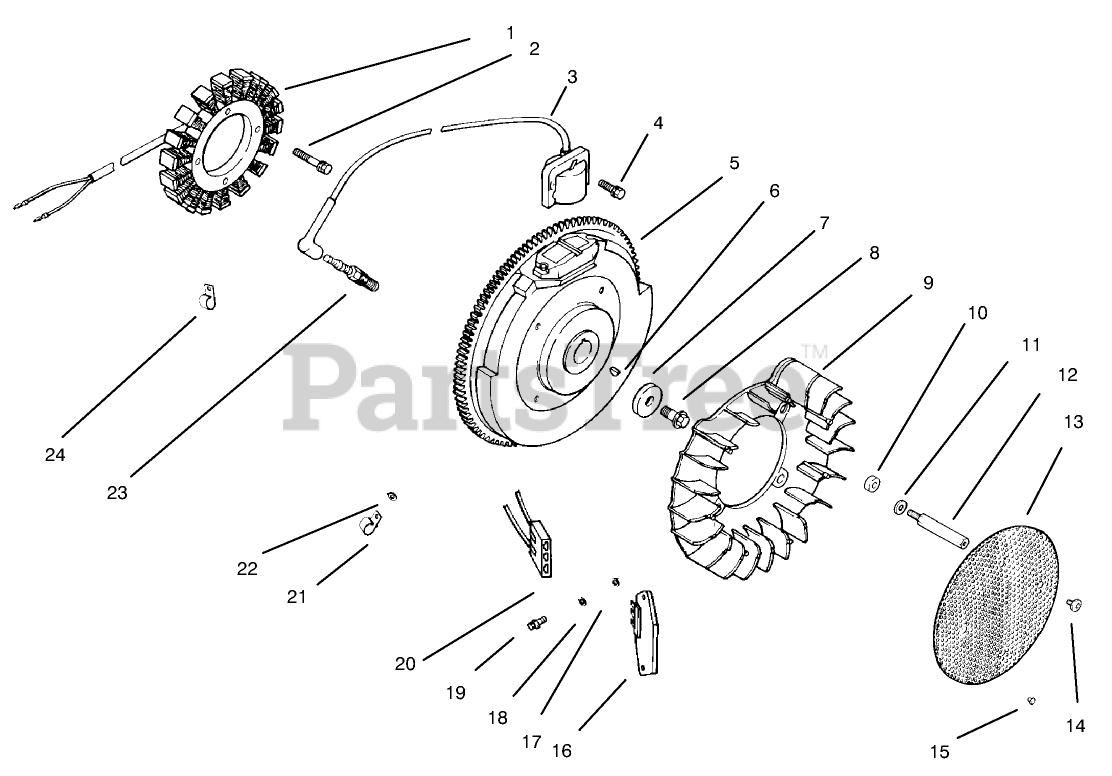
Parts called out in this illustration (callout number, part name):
1	Stator-15 amp
3	Module-Ignition
5	Flywheel
6	KEY (3/16 X 5/8)
7	WASHER-FLAT (13/32)
8	SCREW-FLANGE (M10X1.5X45)
9	Fan
10	Spacer-Fan
11	WASHER-FLAT (1/4)
12	Stud-Grass Screen
13	Screen-Grass
15	Screw-Set (10-24X.25)
16	Rectifier-Regulator, 15 amp
17	WASHER-FLAT (1/4)
18	WASHER-FLAT (.188)
19	SCREW-PHL HD (11-16X.88)
20	Connector (3 contact)
21	CLIP-CABLE
22	WASHER-FLAT (1/4)
23	SPARK PLUG
24	Clip-Cable
